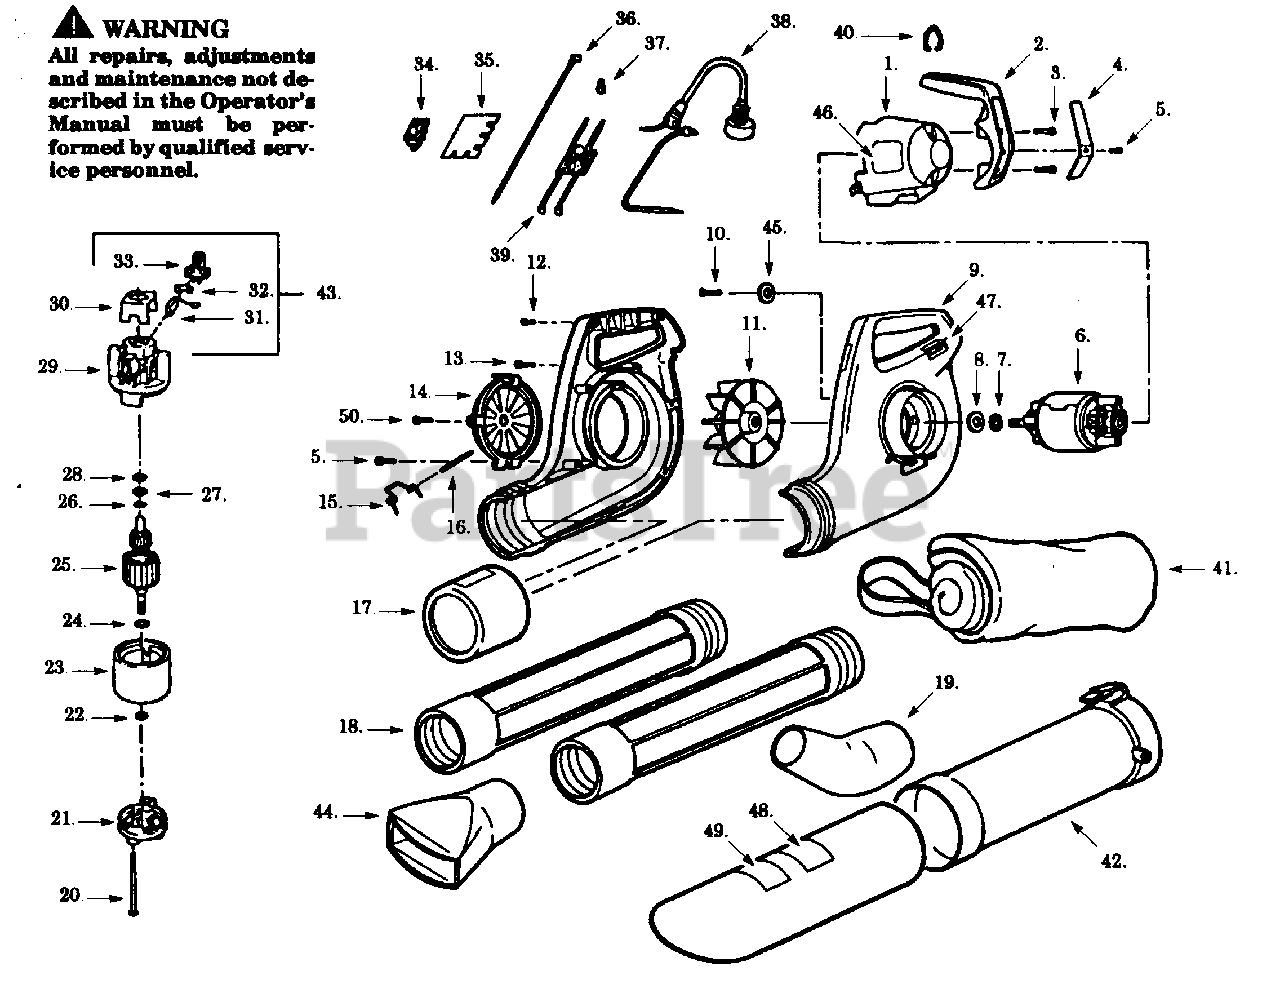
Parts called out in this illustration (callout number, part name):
1	Motor Cover
4	Plate Warning
7	Retaining Ring
9	L.H/R.H. Housing
11	Impeller Ass'y.
14	Inlet Cover
16	Hinge Pin
17	Ferrule Sleeve
18	Outlet Tube
19	Curved Nozzle
21	Endbell Ass'y. (Drive)
23	Field Ass'y.
24	Retaining Ring
25	Armature Ass'y.
26	Retaining Ring
29	Endbell Ass'y. (Brush)
30	Insulator
32	Brush Spring
33	Brush Holder
34	On-Off Switch Ass'y.
35	Mounting Board
36	Leadwire Ass'y.
37	Wire Nut
38	Power Cord Ass'y.
39	P.C. Board Ass'y.
41	Vacuum Bag
42	Vacuum Tube
43	Brush Kit (Incl. 31,32,33)
44	Diffuser Nozzle
46	Motor Cover Label (Not a serviceable part)
47	Switch Position Label
48	Name Plate Label
49	Warning Label-Tube
